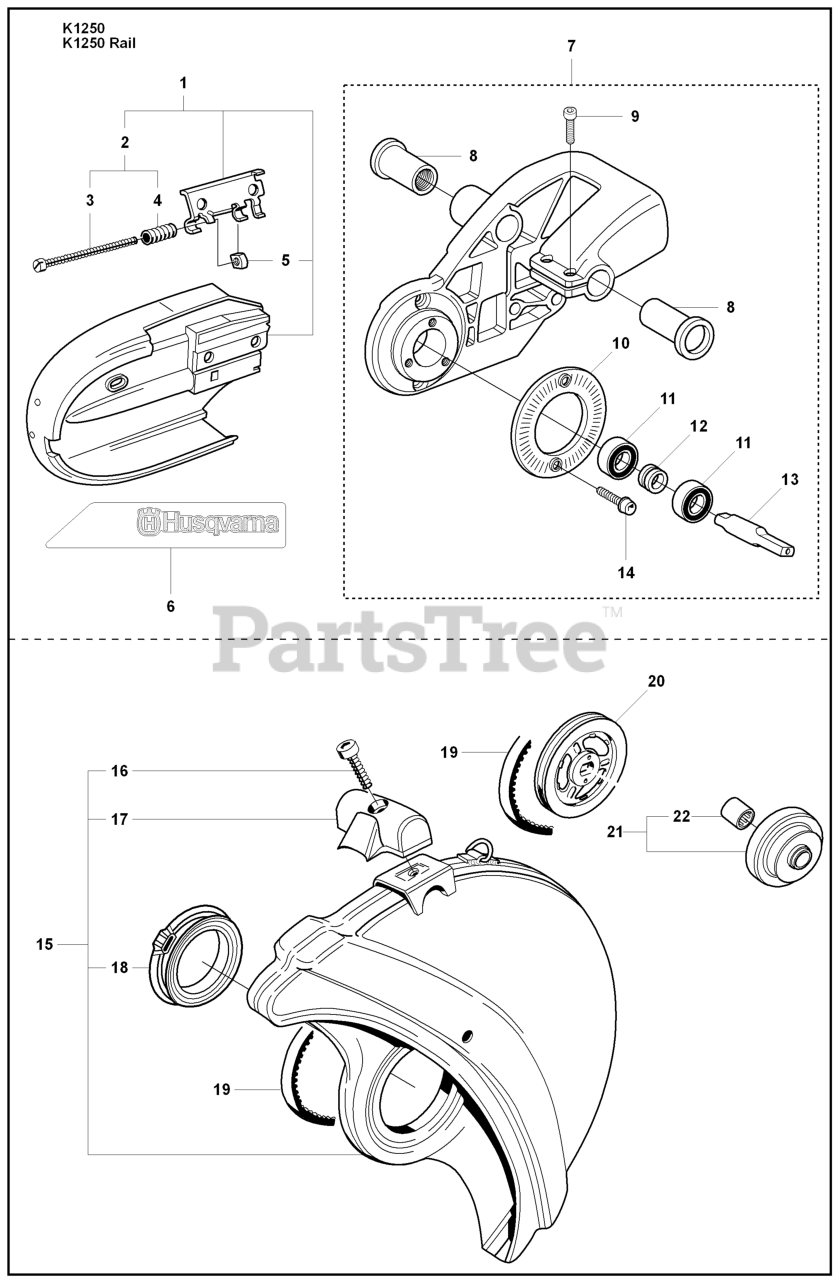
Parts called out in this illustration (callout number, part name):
1	PROTECTOR
2	TENSIONER
7	BEARING HOUSING
7	RP BEARING HOUSING
7	RP BEARING HOUSING RAIL 16"
11	BALL BEARING
15	RP GUARD
15	PROTECTOR
16	SCREW MC6S 5X20
19	BELT
20	%PULLEY
21	WHEEL
21	CLUTCH DRUM 14"
22	SUPPORT BUSHING
